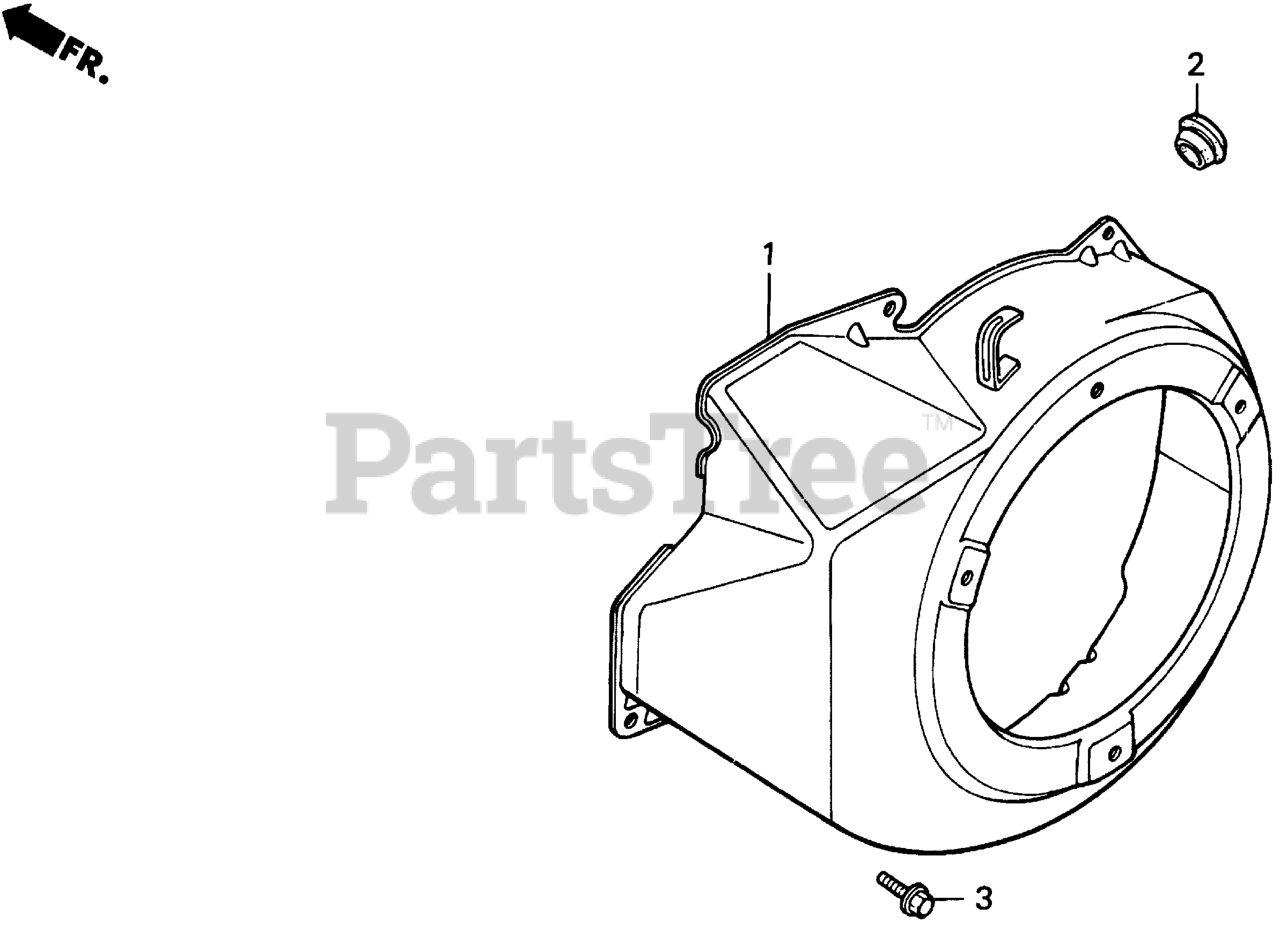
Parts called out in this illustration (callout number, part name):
1	COVER, FAN *R280* (POWER RED)
2	GROMMET, DRAIN HOLE
3	BOLT, FLANGE (6X12) (CT200)
